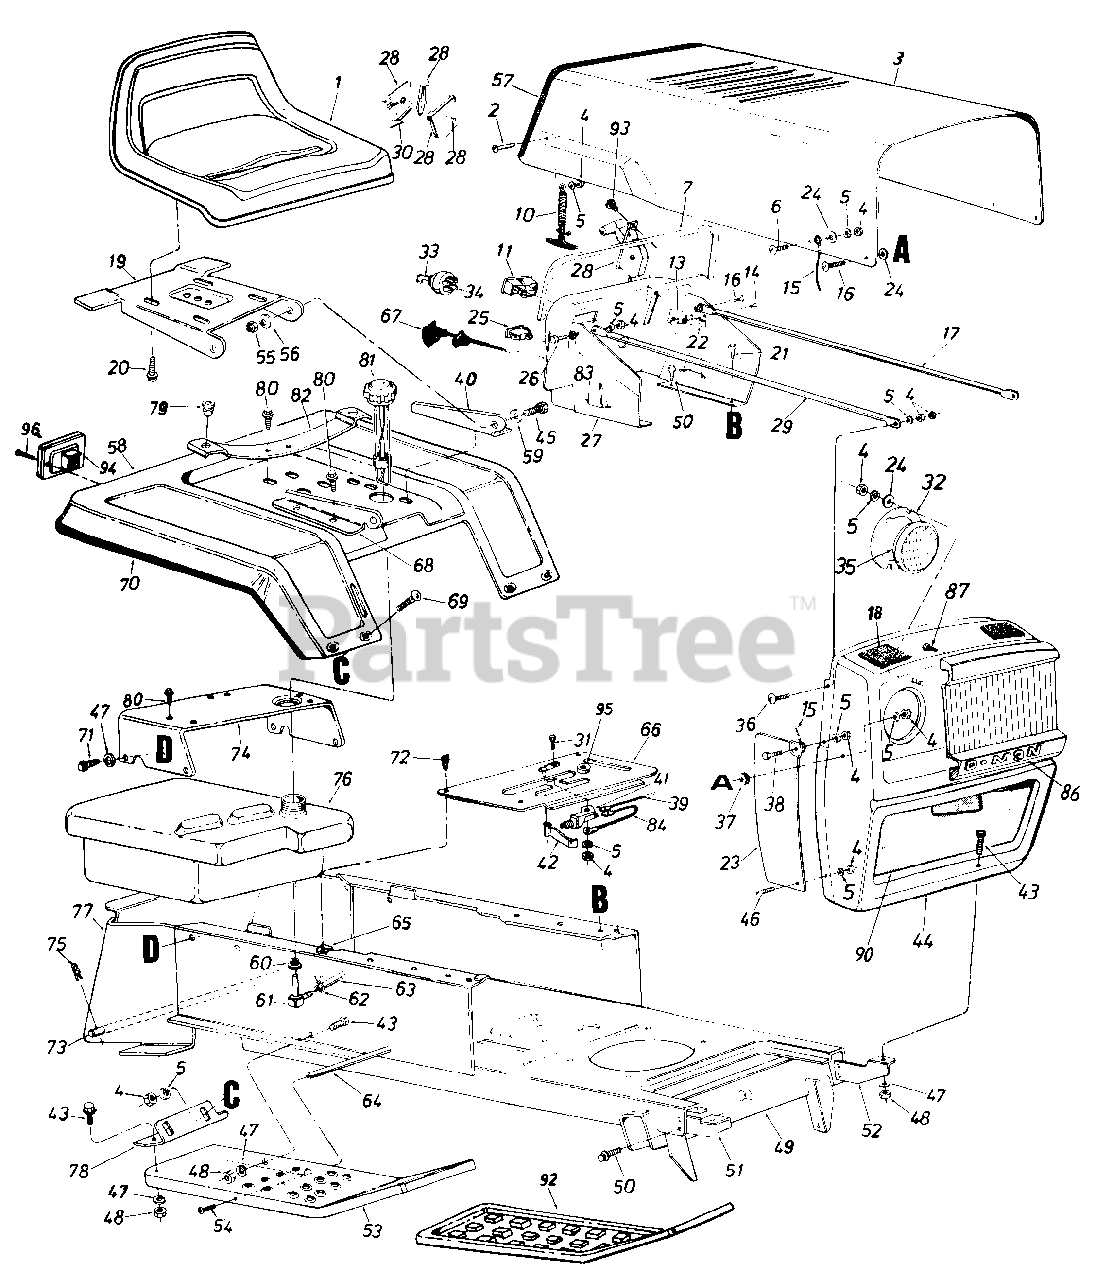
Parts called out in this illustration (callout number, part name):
1	Seat Assembly
2	Truss Mach. Scr. 1/4-20 X .50" Lg.
5	L-Wash. 1/4" Scr.
6	Truss Mach. Scr. 1/4-20 x .50" Lg.
7	Vinyl Molding Strip 29"
10	Hood Latch Ass'y.
11	Ammeter
13	Circuit Breaker 8 Amp.
14	Hex Tap Scr. #10 x .50" Lg.
15	Hood Stop
16	Truss Mach. Scr. 1/4-20 x .75" Lg.
17	Grille Positioning Rod
18	PVC Foam Strip 1/2 X 1.00 x 2.00" Lg.
19	Seat Pivot Brkt.
20	Hex Wash. Hd. AB-Tap Scr. 318 x .75" Lg.
21	Hex Thd. Rolling Scr. 1/4" x .50" Lg.
22	Speed Nut #10Z
23	Grille Side Panel R.H.
24	Fl-Wash. 1/4" I.D.
25	Light Switch
26	Truss Hd. Scr. 1/4-20 x 1.00" Lg.
27	Dash Panel Ass'y.
28	Throttle Control Box Comp.
29	Grille Positioning Rod
30	Throttle Control Cable
31	Hex Bolt 1/4-20 x .50" Lg.
32	Head Lamp Retainer
33	Ignition Key
34	Ignition Switch
35	Head Lamp
36	Truss Machine Scr. 1/4-20 x .75" Lg.
37	Rubber Wash. .50" I.D. x 1.00 O.D. x .25 Thk.
38	Truss Mach. Scr. 1/4-20 x .5"
39	Reverse Lockout Wire Harness
40	Seat Bracket L.H.
41	Safety Switch
42	Switch Actuator Spring Lever
43	Hex Scr. 5/16-18 x .75" Lg.
44	Grille Ass'y.
45	Hex Bolt 5/16-18 x .75" Lg.
46	Truss Mach. Scr. 1/4-20 x .5
47	L-Wash. 5/16" I.D.
48	Hex Nut 5/16-18 Thd.
49	Lower Frame Ass'y.
50	Hex Thd. Rolling Scr. 5/16" x.75" Lg.
51	Grille Mount Brkt. R.H.
52	Grille Mount Brkt. L.H.
53	Running Board R.H.
54	Truss Mach. Scr. 5/16-18 x .75" Lg.
55	Hex Cent. L-Nut 5/16-18 Thd.
56	Bell-Wash. .34" I.D. x .88 O.D.
57	Vinyl Moulding Strip 30"
58	Fender Ass'y.
59	Bell-Wash. .34" I.D. x .88" O.D.
60	Bushing
61	90ø Nipple
62	Hose Clamp 3/8"
63	Gas Line 46" Lg.
64	Running Board Rod
65	Speed Nut #10-24
66	Transmission Cover Ass'y.
67	Choke Control Comp.
68	Seat Bracket R.H.
69	Carr. Bolt 1/4-20 x .50" Lg.
70	Trim Strip 81" Lg.
71	Hex Thd. Rolling Scr. 5/16-24 x .75" Lg.
72	Truss Hd. Scr. #10 x .50" Lg.
73	Hitch Rod
74	Seat Mounting Channel
75	Internal Cotter Pin
76	Gas Tank
77	Hitch Plate
80	Hex Wash. Hd. Self-Tap Scr. 5/16-18 x .50" Lg.
81	Gas Gauge
82	Seat Spring
83	External Wash. 1/4" I.D.
84	Electric Wire
86	Headlight Bezel
87	Self-Tap Scr. #8 x .5" Lg.
90	Grille Screen
92	Foot Pad
93	Truss Mach. AB-Tap Scr. #10 x .50" Lg.
94	Tailight
95	Snap Bushing
96	Truss AB-Tap Scr. #6 x .62" Lg.
